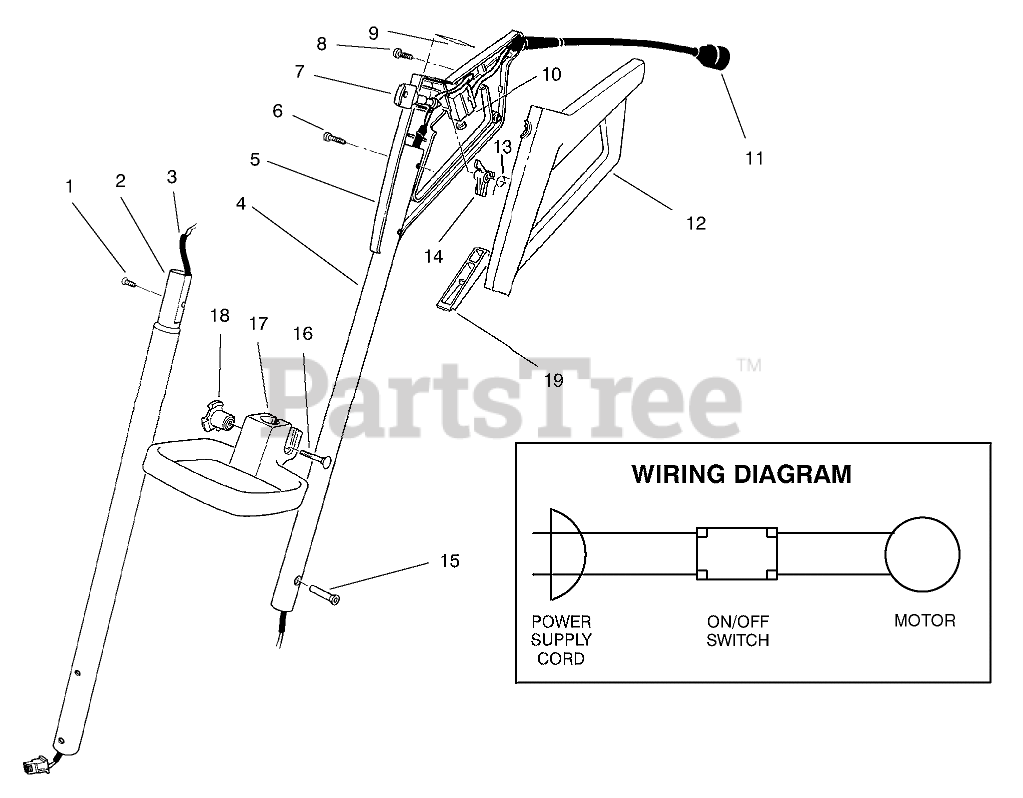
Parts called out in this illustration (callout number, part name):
1	SHOULDER SCREW
2	LOWER TUBE P. SHOVEL
3	WIRE HARNESS, P.S.
4	UPPER TUBE P. SHOVEL
5	PS-CONTROL GRIP, RH
6	SCREW-PPH
8	SCREW
9	UL GRIP DECAL
10	SWITCH-STARTER
11	SUPPLY CORD, 1200
12	PS-CONTROL GRIP, LH
13	TORSION SPRING
14	LOCKOUT
15	COUNTER SUNK NUT
16	BOLT-CARR
17	PS-ADJUST HANDLE-BLK
18	HANDLE KNOB
19	SWITCH BAR,POWER SHOVEL
